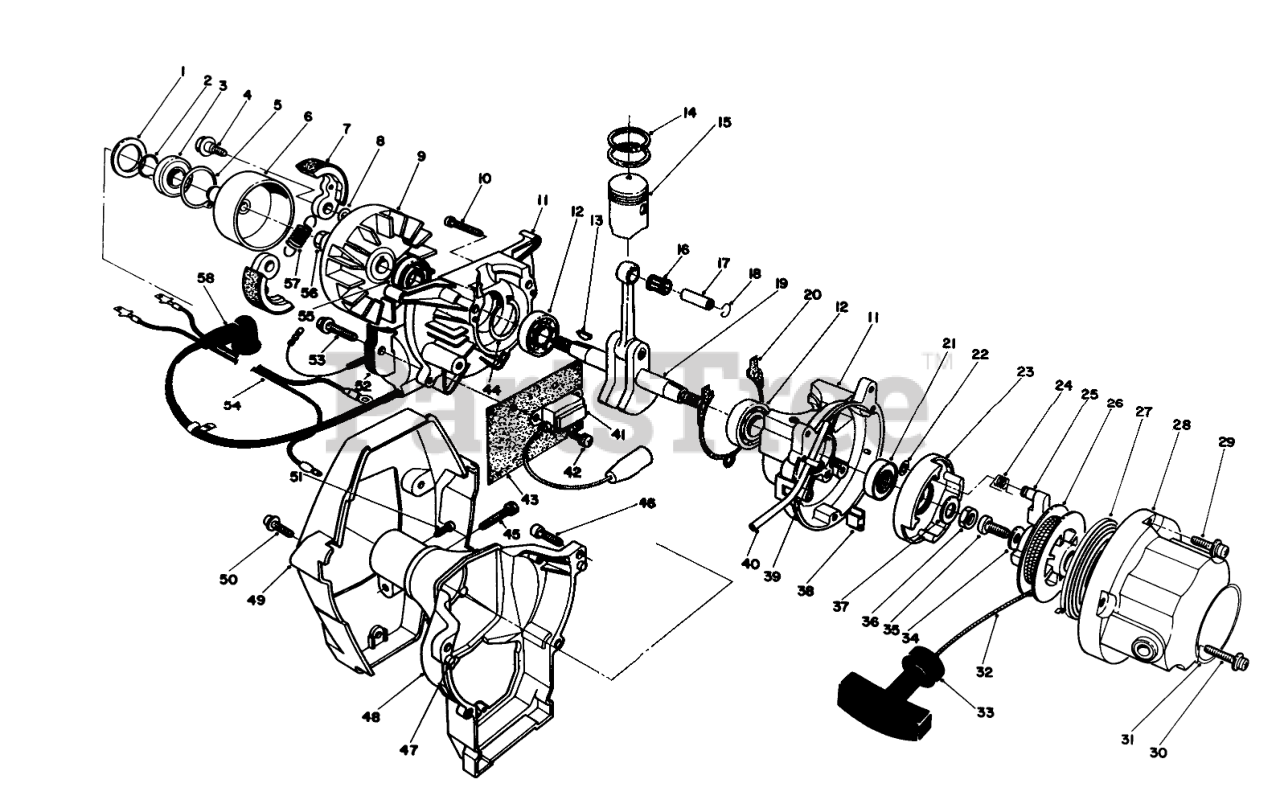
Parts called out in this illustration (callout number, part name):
1	Washer
2	SNAPRING
3	BEARING
4	CLUTCH BOLT
5	SNAPRING
6	Drum-Clutch
7	Shoe-Clutch
8	Washer
9	Flywheel
10	Screw
11	Crankcase Assembly (Incl. Ref. #10)
12	BEARING
14	PISTON RING
15	PISTON
16	NEEDLE BEARING
17	Pin-Piston
19	Crankshaft
20	Gasket-Crankcase
21	OIL SEAL
22	E-Ring
23	STARTER PULLEY
24	RETURN SPRING
25	RATCHET
27	SPRING
28	Case-Starter
29	SCREW W/WASHER
30	SCREW W/ WASHER
31	Decal
32	Rope-Starter
33	Knob-Starter
34	Washer
35	Screw
37	Washer
39	Clamp
40	Tube-Fuel
41	TRANSISTOR UNIT
42	SCREW W/ WASHER
43	Plate
44	Snap Ring
46	Screw
47	Knock Pin
48	Case-Clutch
49	Cover-Fan
50	Screw
51	Screw
53	BOLT AND WASHER
54	LEAD WIRE
55	Oil Seal
57	Spring
58	CAP-PLUG
